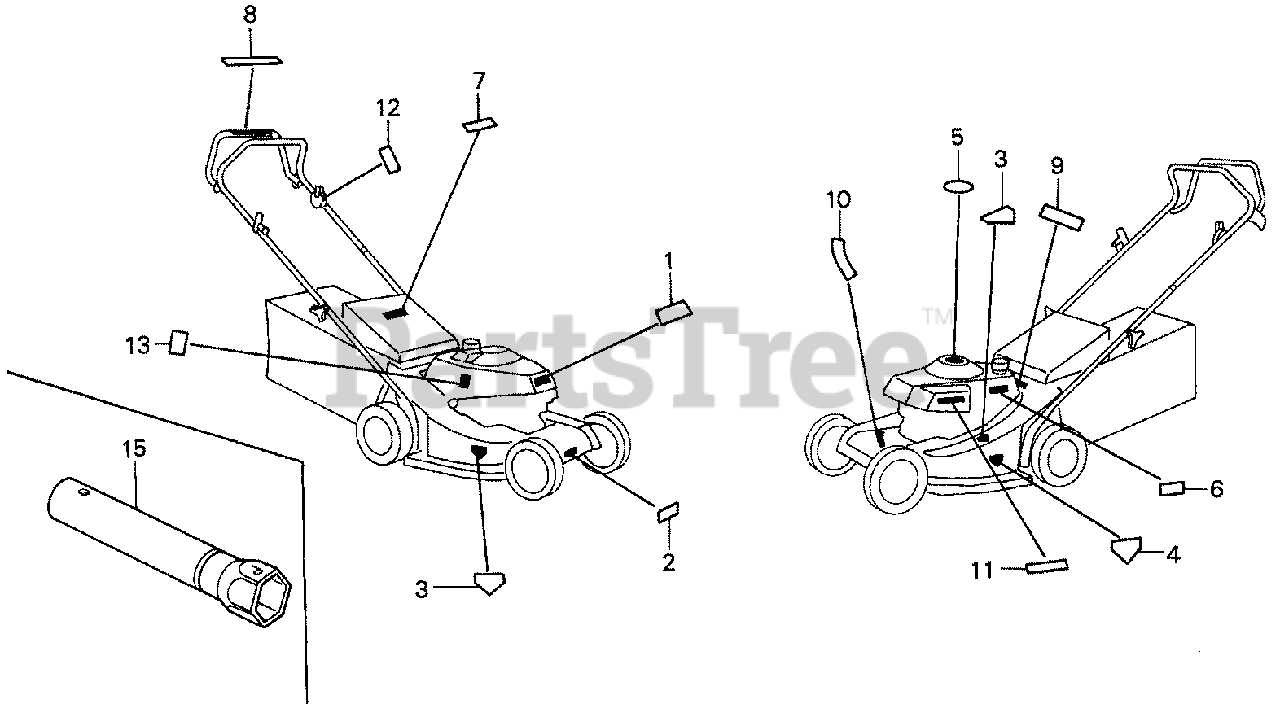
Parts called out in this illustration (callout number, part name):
2	LABEL A, HOUSING CAUTION
2	CAUTION A, HOUSING (ENGLISH)
2	MARK A, HOUSING DANGER (E)
3	CAUTION B, HOUSING (ENGLISH)
4	CAUTION C, HOUSING
4	LABEL C, HOUSING CAUTION
5	CAUTION, OPERATOR (ENGLISH)
6	LABEL, FUEL CAUTION (ENGLISH)
7	LABEL, DISCHARGE GUARD CAUTION
8	MARK, BLADE CONTROL
9	PLATE, MANUFACTURE
9	PLATE, MANUFACTURE (NOT AVAILABLE)
10	LABEL, PLUG CAUTION (ENGLISH)
11	MARK, AIR CLEANER CAUTION (ENGLISH)
12	MARK, THROTTLE
13	MARK, OIL CAUTION
15	WRENCH, SPARK PLUG (NOT AVAILABLE)
